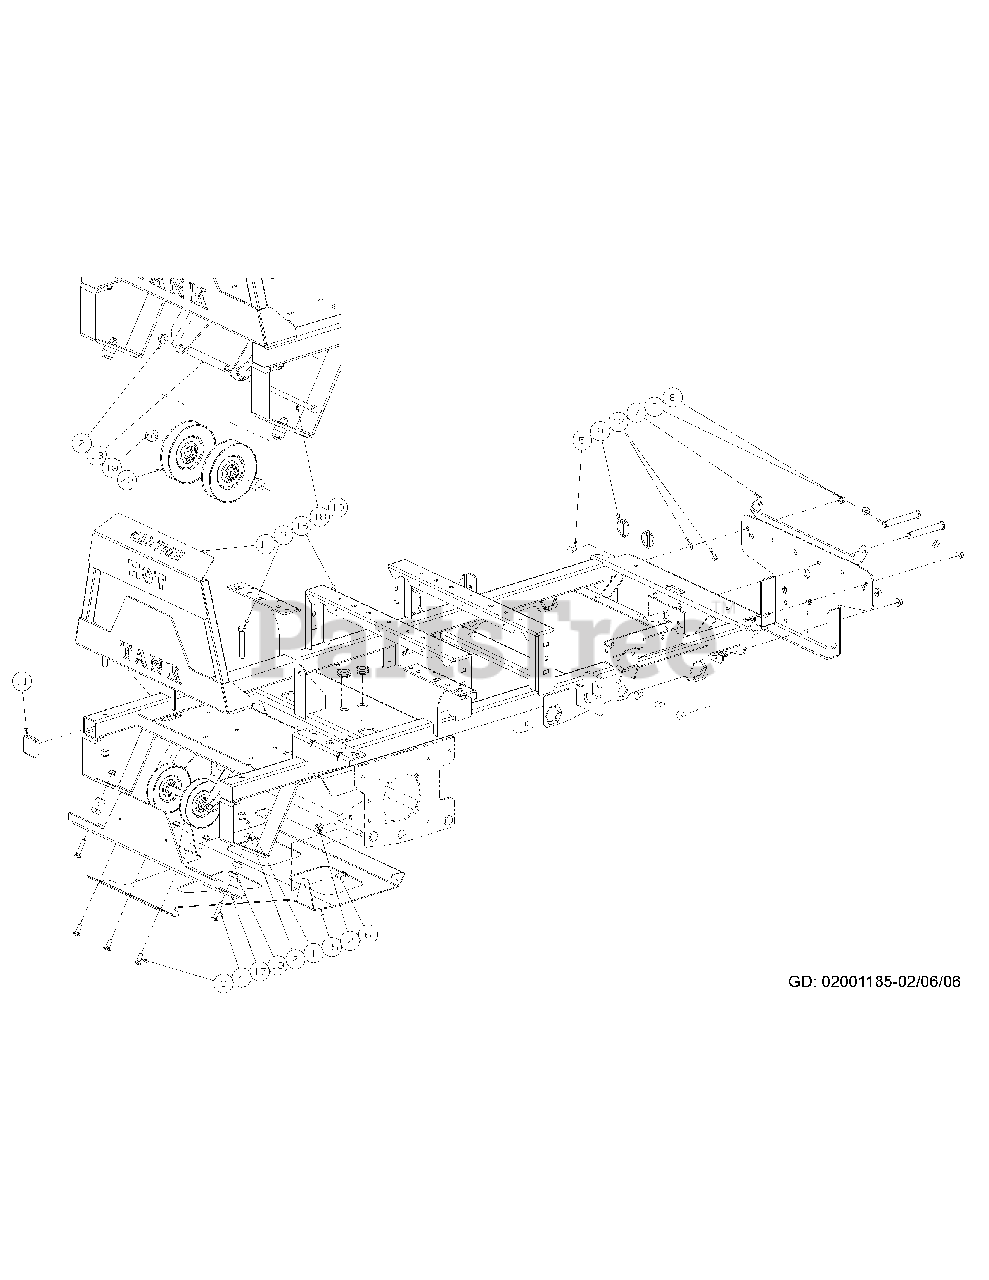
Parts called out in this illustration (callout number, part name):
1	Lock Nut, Nylon Insert, 1/2-13
2	Hex Nut, 3/8-16 Flange Lock
3	Hex Head Cap Screw, 1/2-13 x 3.00
4	Carraige Bolt, 3/8-16 x 1.75
5	Carriage Bolt, 3/8-16 x .75 Long
6	Carriage Bolt, 3/8-16 x 1.0
7	Bracket Assembly, Frame, Front
8	Clevis Pin, .625 Dia x 4.375 Long
9	Linch Pin, 3/16 Dia.
10	Grommet, .75 ID
11	Plug, Square Tube
12	Push Retainer, 3/8
13	Spacer, .385 ID x .625 OD x 4.89
14	Muffler Guard Assembly
15	Skid Plate
16	Frame Assembly
17	Guard Bracket
18	Hex Head Cap Screw, 3/8-16 x 8.50
19	Spacer, .406 ID x 1.00 OD x .380
20	Idler Pulley, 5.06 Dia.
